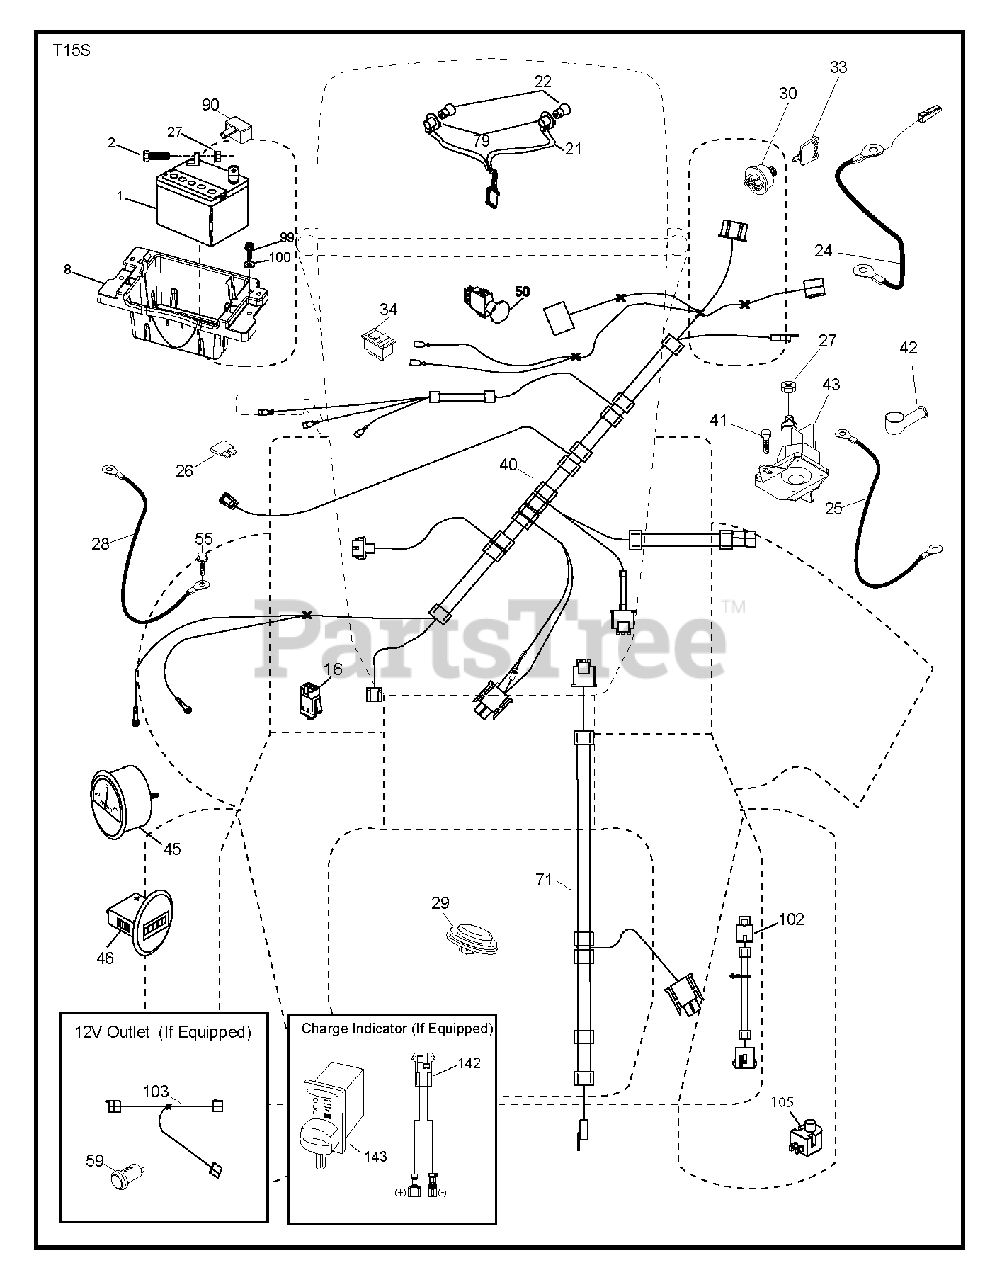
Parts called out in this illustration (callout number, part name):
1	REPL BY 532 12 38-99
2	BOLT.HEX.1/4.X.3/4.DICHROMATE
8	TRAY.BATTERY BOX.FRONT
16	SWITCH INTERLOOK PUSH-IN
21	HARNESS.LIGHT W/4152J BULBS
22	LIGHTBULB
24	Battery Cable with Wire, Front 8 Ga 8
25	Starter Cable, 8 Ga 17.5"
26	FUSE 20AMP
27	NUT
28	Ground Cable, 21" Black 8 Ga 90T
29	SWITCH.SEAT.DELTA.OPC.
30	SWITCH.IGN.DELTA.W.LGH.ROS
33	KEY.CHAIN.BLISTER.PACK.GEN.USA
34	SWITCH LT
40	HARNESS.TEX.DASH.MAN.REAR BATT
41	SCREW
42	TERMINAL COVER
43	SOLENOID.W/BRASS.PLUNGER
45	AMMETER.ROUND.BLACK.DELTA
50	PTO Switch, 8-Terminal STD Black
55	SCREW 5/16"
71	HARNESS-CHASSIS SUB
79	BULB HOLDER ASM.
90	COVER.TERMINAL.BATTERY
99	SCREW HEXWSHR 1/4-20X3/4
102	HARNESS.PIGTAIL.VARIATOR.SD
105	REVERSE SWITCH
